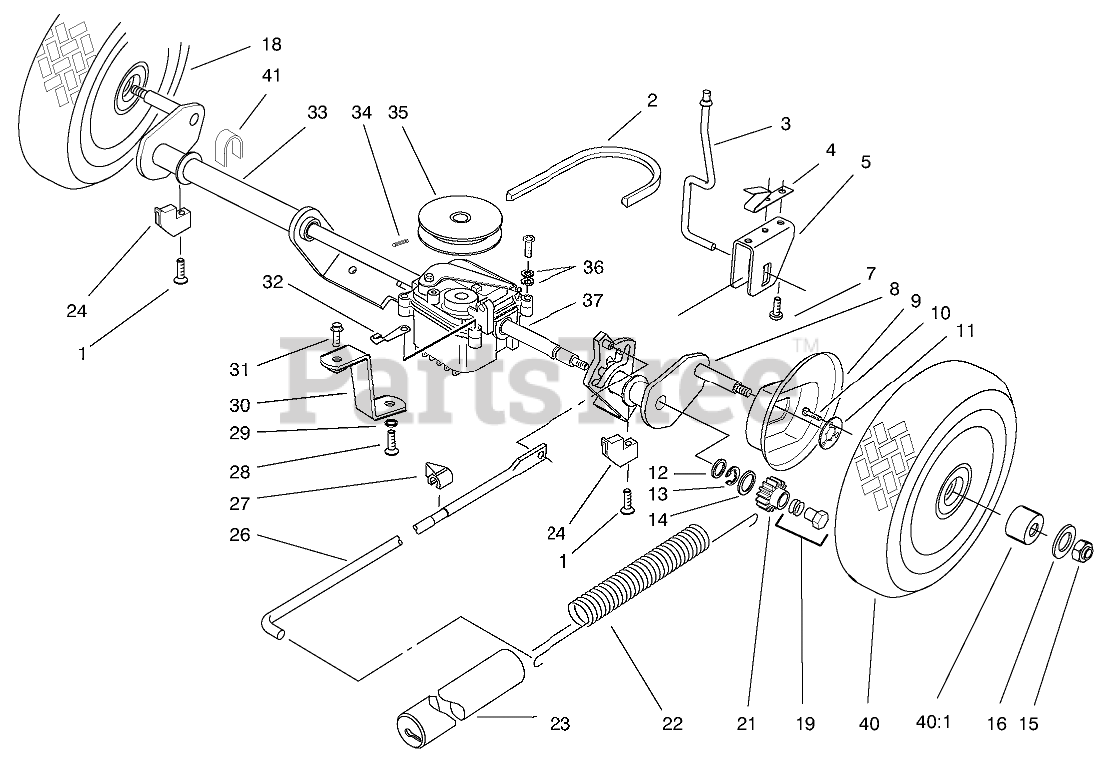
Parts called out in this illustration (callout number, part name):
1	SCREW-RETAINER
2	BELT - V
3	ROD-TRIGGER
4	SPRING-RETURN, TRIGGER
5	SADDLE-HEIGHT OF CUT
7	SCREW-RH
8	AXLE - REAR
9	COVER-WHEEL
10	SCREW - WHEEL GEAR
11	GEAR-WHEEL
12	WASHER-COVER
13	WASHER-AXLE
14	WASHER-GEAR
15	NUT-HH
16	WASHER-WHEEL
18	WHEEL-REAR
19	LEFT BUSHING ASM
22	SPRING-COUNTERBALANCE
23	COVER-SPRING
24	RETAINER-AXLE
26	ROD-LINK
27	INDICATOR-HEIGHT OF CUT
28	SCREW-BRACKET
29	WASHER - BRACKET
30	BRACKET - GEARBOX
31	SCREW - BRACKET
32	HOLDER - CABLE
33	AXLE - REAR
34	PIN - ROLL
35	PULLEY - GEARBOX
36	WASHER
37	ASSEMBLY - GEAR CASE
40	WHEEL-SMART, REAR
40:1	BUSHING
41	CAP-AXLE, REAR
